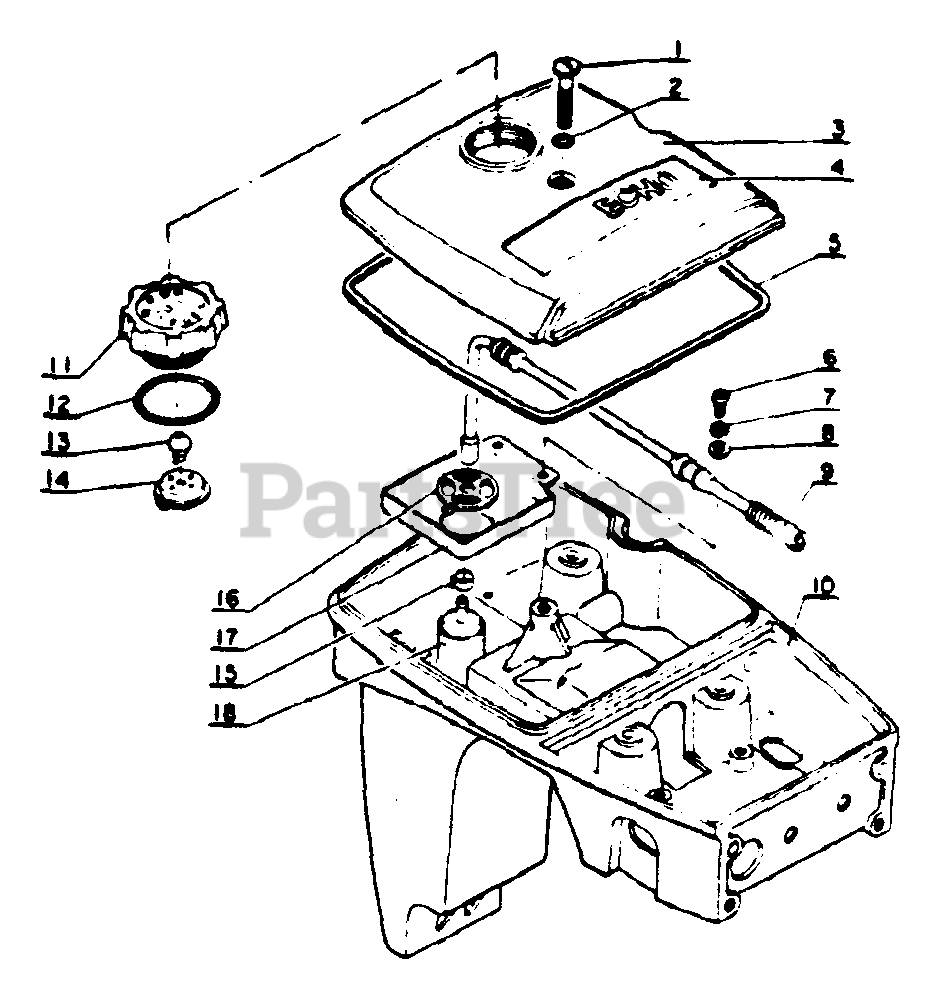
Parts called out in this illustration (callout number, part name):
1	SCREW
2	O-RING
3	LID, FUEL TANK
4	LABEL - ECHO
5	GASKET, FUEL TANK
6	SCREW - 4X10
7	LOCKWASHER - 4
8	WASHER - 4
9	PIPE - FUEL
10	TANK, FUEL
11	CAP
12	O-RING
14	HOLDER, VENT
15	RETAINER, PIPE
16	Fuel pipe spacer
17	Fuel pipe supporter
18	FILTER, FUEL
